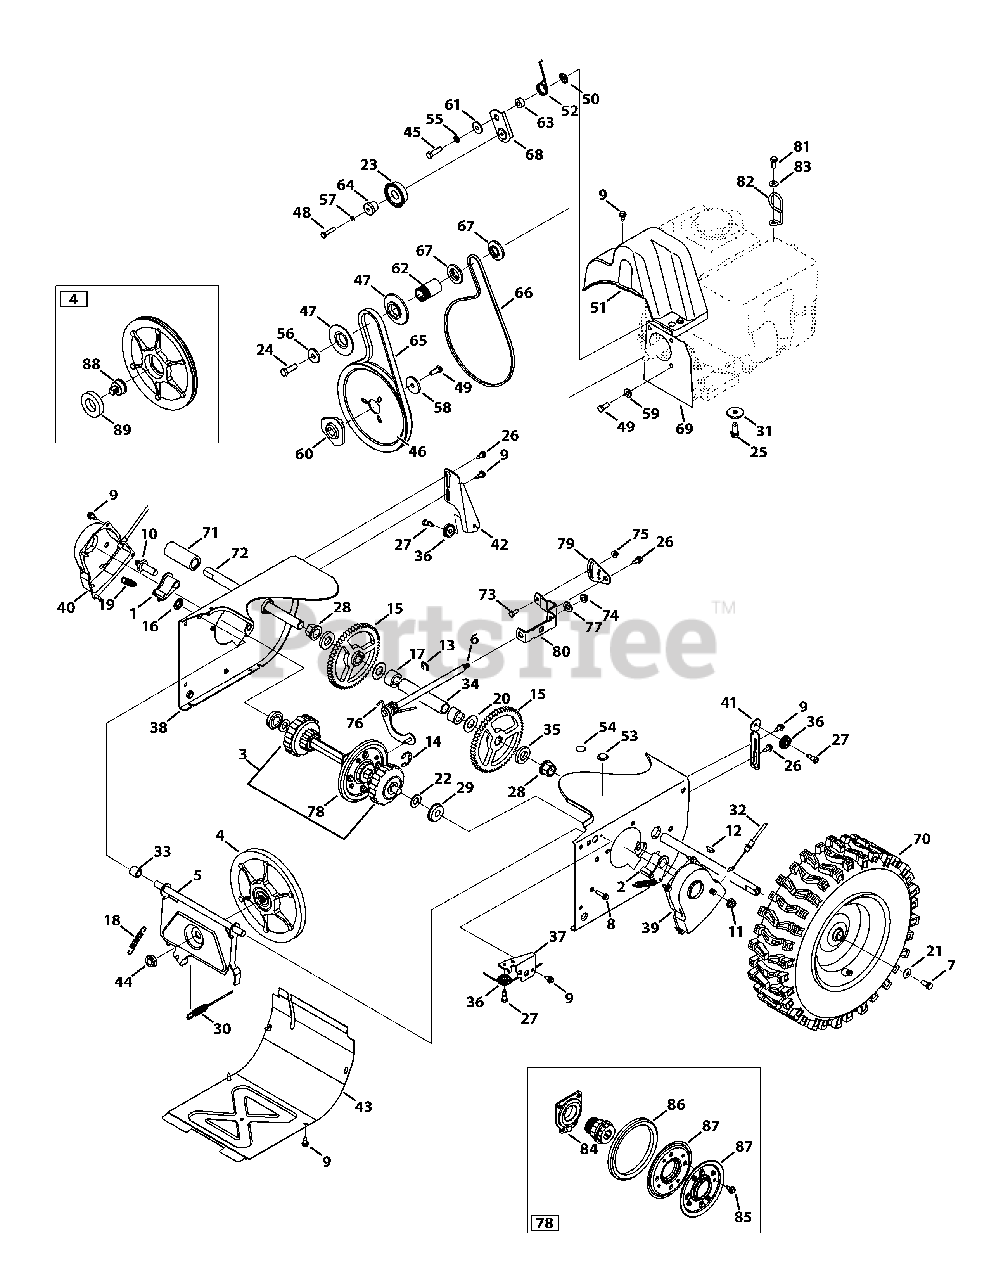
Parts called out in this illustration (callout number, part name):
1	Dogg Assembly, RH
2	Dogg Assembly, LH
3	Drive Shaft Assembly
4	Friction Wheel Disc Assembly
5	Friction Wheel Support
6	Rod Shift Assembly
7	Hex Head Screw, 5/16-24 x .750
8	Screw, 1/4-20 x 1.000
9	Screw, 1/4-20 x .625
10	Actuator Shaft
11	Nut, Flangelock, 3/8-16
12	Hi-Pro Key, 3/16 x 3/4 DIA
14	Retainer Ring
16	Nut, Speed, .500
17	Spacer, .76 x .75
18	Extension Spring, .380 x 2.500
19	Extension Spring, .500 x 1.71
20	Washer, Flat, .76 x 1.49
21	Washer, Bell, .340 x .872
22	Washer, Flat, .58 x 1.125
23	Pulley Assembly
24	Hex Head Screw, 3/8-24 x 1.25
25	Taptite Sems Screw, 3/8-16 x 1.000
26	Screw, Shoulder, .368 x .113 x 1/4-20
27	C Screw, Shoulder, .340 x .335 x 1/4-28
28	Hex Flange Bearing, .75 ID
29	Ball Bearing, .5625 x 1.375 x .4375
30	Drive Clutch Cable
31	Washer, Flat, .38 x 1.38
32	Steering Cable
33	Spacer, .508 x .75
34	Axle Support Tube
35	Spacer, Axle
36	Roller Cable
37	Auger Cable Guide Bracket
38	Wheel Drive Frame
39	Shaft Retainer, LH
40	Shaft Retainer, RH
41	Auger Clutch Cable Guide Bracket
42	Drive Clutch Cable Guide Bracket
44	Nut, Flange, 5/8-18
45	Hex Head Screw, 5/16-24 x 1.25
46	Auger Pulley, 8.1 x .5
47	Pulley, Half, 4L-V x 2.600
48	Taptite Screw, 1/4-20 x 1.250
49	Hex Head Screw, 5/16-24 x .875
50	Nut, Push-On, .25 DIA
51	Belt Cover, 4-Way (528)
51	Belt Cover (524)
52	Spring, Torsion, .850 x .333
53	Plug, 3/8 ID
54	Plug, 1/2 ID
55	Washer, Lock, 5/16
56	Washer, Flat, .406 x 1.25
57	Washer, Lock, 1/4
58	Washer, Flat, .34 x 1.50
59	Shoulder Spacer
60	Pulley Adapter, .75 DIA
61	Spacer, Shoulder, .3175 x .500
62	Spacer, .875 x 1.185
63	Spacer, .340 x .750
64	Spacer, Shoulder, .260 x .785
65	Belt, .500 x 37.00 (528)
65	Belt, .500 x 35.06" (524)
66	V Belt, 3/8 x 35.68" (528)
66	V Belt, 3/8 x 34.4" (524)
67	Pulley, Half, 3/8-V x 1.7160
68	Drive Idler Bracket
69	Cover Plate (528)
69	Cover Plate (524)
70	Wheel, LH (528)
70	Wheel, RH (528)
70	Wheel, LH (524)
70	Wheel, RH (524)
71	Spacer, 1.25 x .75 x 3.00
72	Axle, .75 x 11.12
73	Hex Head Screw, 1/4-20 x .620
74	Nut, Flangelock, 5/16-18
75	Nut, Flangelock, 1/4-20
76	Spring, Torsion, .750 x .968
77	Washer, Flat, .469 x .875 x .105
78	Friction Wheel Assembly
79	Speed Selector Pivot Bracket
80	Speed Selector Shift Bracket
81	Hex Head Screw, 1.25 x 20
82	Cabke Guide
83	Washer, Flat, .330 x .630
84	Bearing Assembly, Friction Wheel
85	Screw, 1/4-14 x .625
86	Friction Wheel, 5.5 OD
87	Friction Wheel Plate
88	Friction Pin, Disc Bearing
89	Ball Bearing, 30 x 55 x 13
